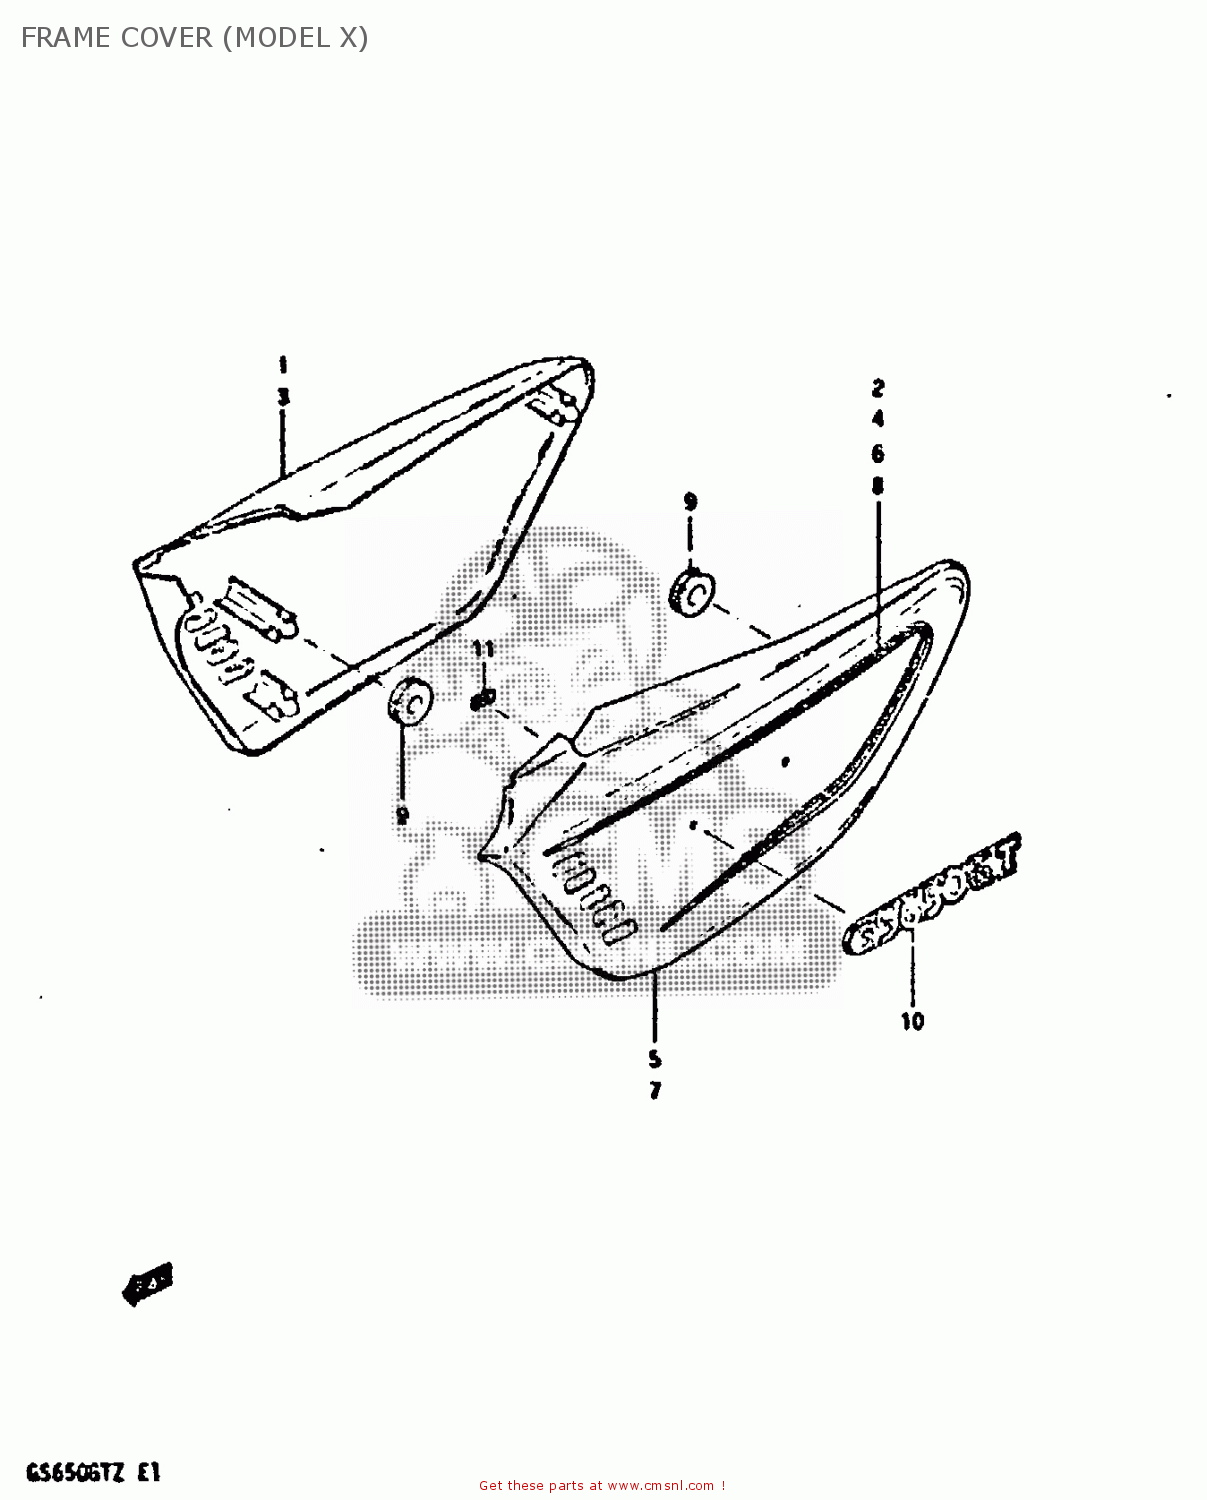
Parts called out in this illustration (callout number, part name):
1	COVER,FRAME,RIGHT
2	TAPE,FRAME COVER
3	COVER, FRAME RH (RED)
4	TAPE,FRAME COVER
5	COVER,FRAME,LEFT
6	TAPE,FRAME COVER
7	COVER, FRAME LH (RED)
8	TAPE,FRAME COVER
9	CUSHION
10	EMBLEM
11	NUT
